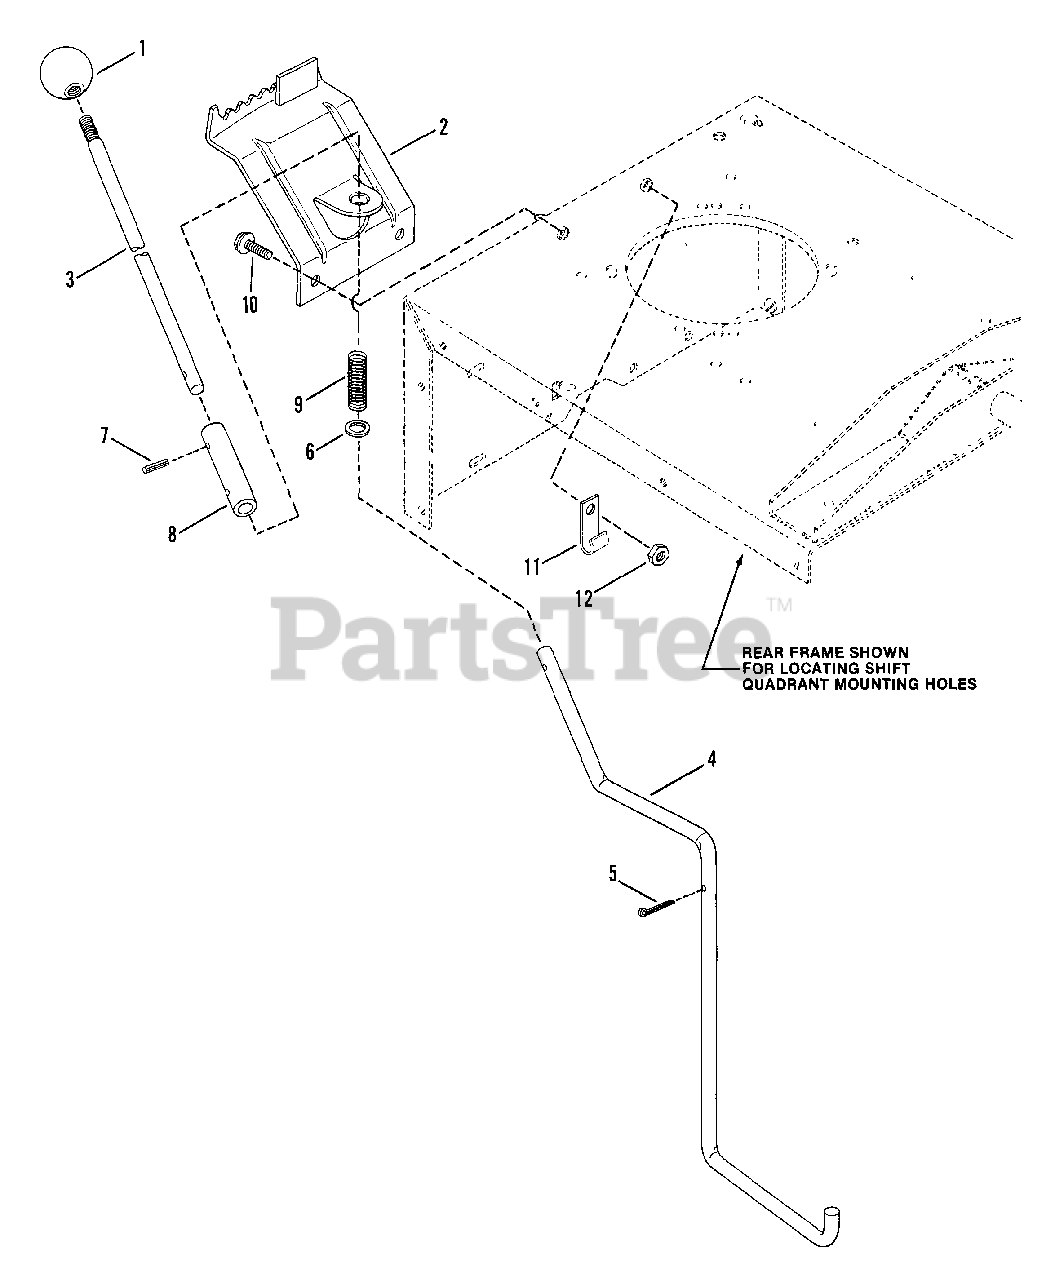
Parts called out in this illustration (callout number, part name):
1	KNOB, Shift Lever, Upper
2	QUADRANT, Shift
3	LEVER, Shift, Upper
4	LEVER, Shift, Lower
5	COTTER-PIN, 3/32 x 1"
6	WASHER, Shim
7	ROLL-PIN, 3/16 x 3/4"
8	CONNECTOR, Shift Lever
9	SPRING
10	SCREW, 5/16-18 x 3/4" H.W.H. Self-Tapping
11	CLIP, Harness
12	NUT, 5/16-18 Hex Center Lock
